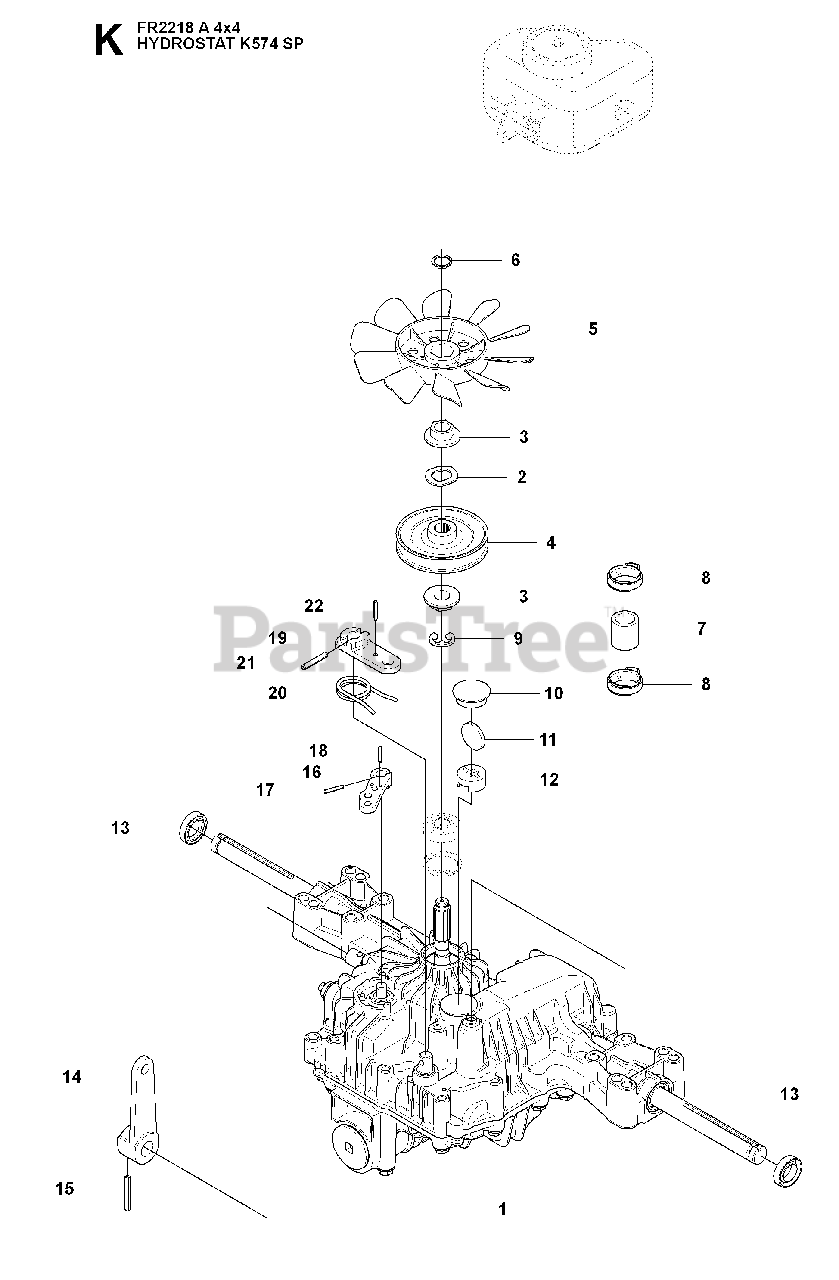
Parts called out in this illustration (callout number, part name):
1	HYDRAULMOTOR
2	WASHER **
5	FAN
6	RETAINING RING **
8	CLAMP
12	MAGNET HOLDER
13	SEALING
14	CONTROL LEVER
20	RETURN SPRING
